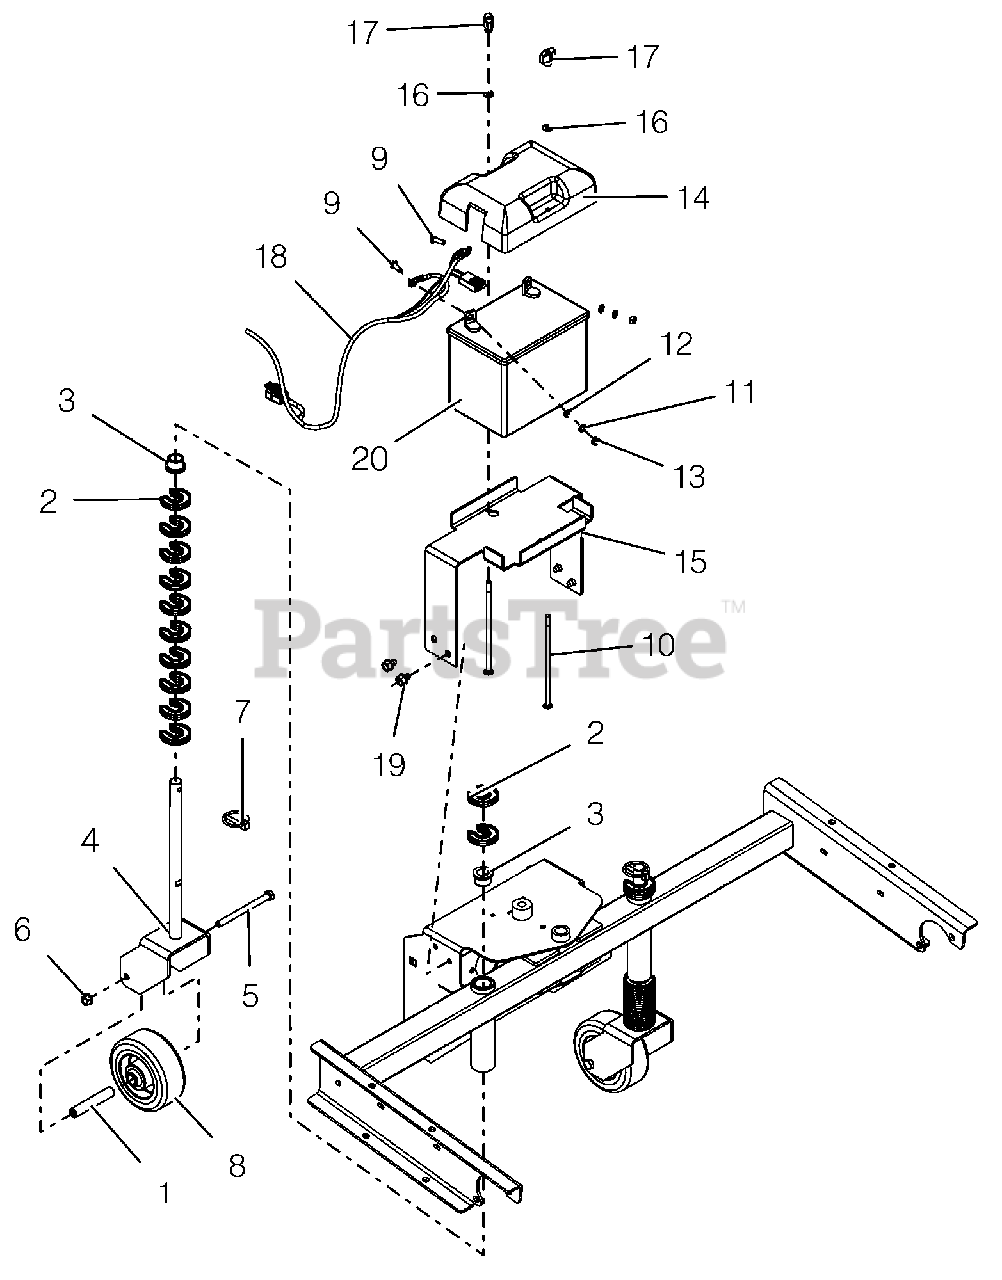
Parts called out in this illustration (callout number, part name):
1	SPACER, CASTER WHEEL
2	CLIP-HOC FIXED
3	BUSHING, FLANGE .75X.75X1.0
4	FORK, CASTER
5	@BLT-HEX .38-16X4.50 GR5 YWZC
6	@NUT-LK-TOP-FLG .38-16 YWZC
7	PIN, 1/4X1-9/16 LYNCH
8	WHEEL, CASTER - 5"OD
9	@BLT-HEX .25-20X.75 GR5 YWZC
10	@BLT-RDHDSQNK .25-20X7.00 G2YZ
11	@WSHR-LK .25X.062 REG YWZC
12	WSHR-FL-STL .265X.50X.087YWZC
13	@NUT-HEX .25-20 YWZC
14	COVER, BATTERY
15	TRAY, BATTERY - POWER BRUSH
16	@WSHR-FL-STL.281X.62X.065 YWZC
17	KNOB, WING - .25-20 UNC
18	HARNESS,ELEC - ENGINE 12V
19	@SCR-TAP .38-16X.50 HWH TR YWZ
20	BATTERY, 300 CCA 10U1L
